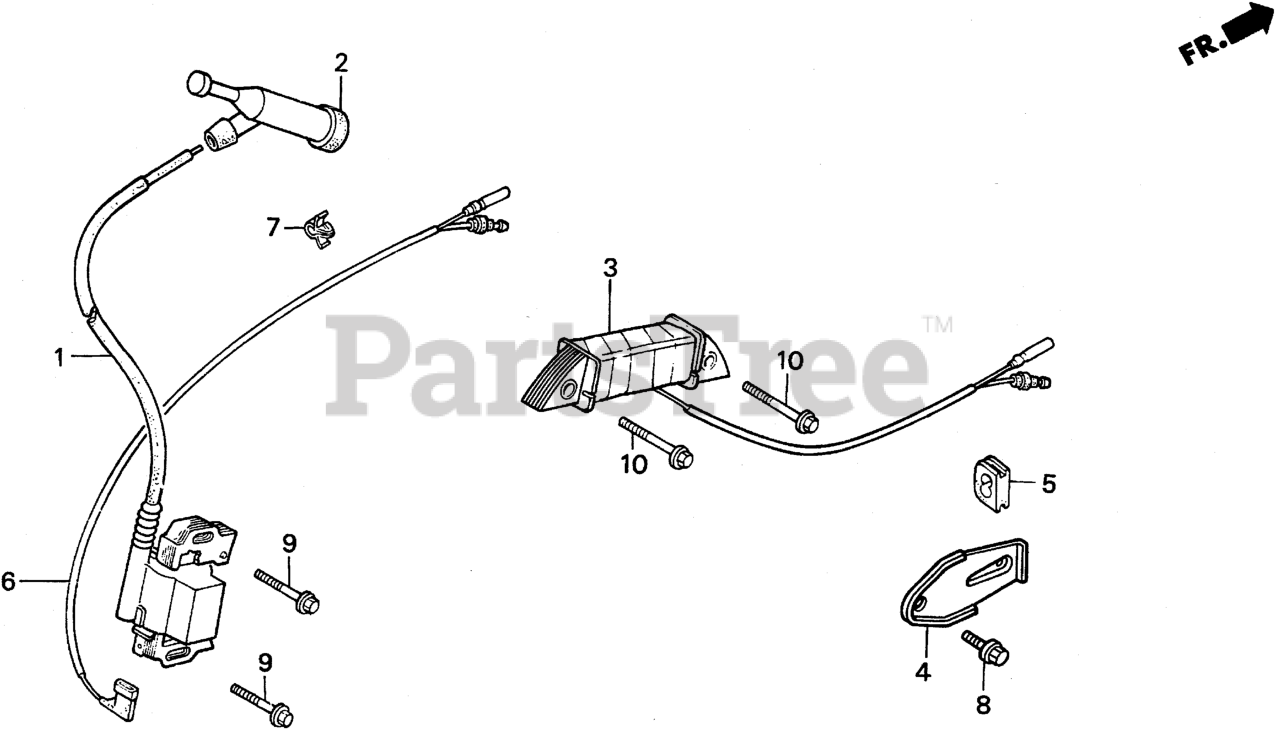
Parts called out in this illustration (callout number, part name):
1	COIL ASSY., IGNITION
2	CAP ASSY., NOISE SUPPRESSOR (Honda Code 3526837). (NICHIWA Y-EZ RTFM256)
3	COIL ASSY., LAMP (12V/15W)
4	CLAMP, WIRE
5	GROMMET, WIRE
6	WIRE, STOP SWITCH (430MM)
7	HOLDER, STOP SWITCH WIRE Use up to Engine SN 2056819.
8	BOLT, FLANGE (6X12) (CT200)
9	BOLT, FLANGE (6X28) (CT200) Use up to Engine SN 1530314.
10	BOLT, FLANGE (6X23)
